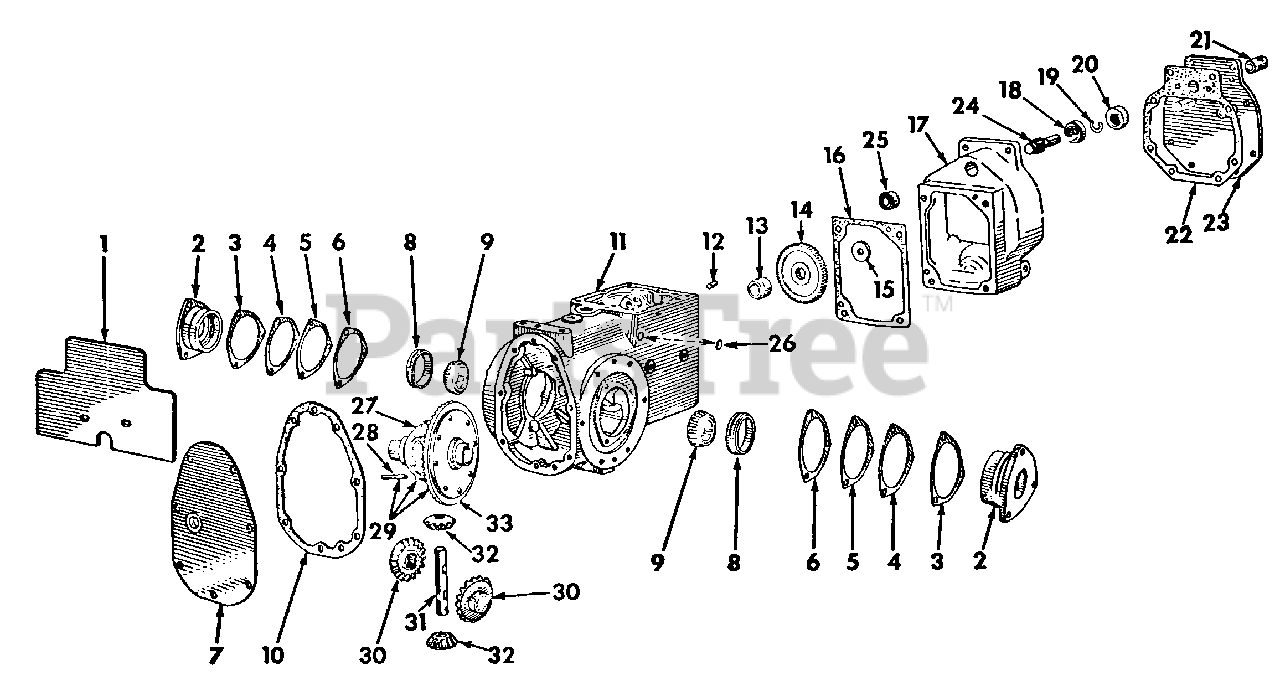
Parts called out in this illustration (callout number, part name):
1	Not used in this application
2	Cage w/Cup IH-ST974, Differential Brg
3	Shim, Differential Brg Retainer, .004
4	Shim, Differential Brg Retainer, .007
5	Shim, Differential Brg Retainer, .0149
6	Shim, Differential Brg Retainer, .0299
7	Plate Assy, Transmission Case Rear Cover
8	Bearing, Differential Cup
9	Bearing Assy, Differential Cone
10	Gasket, Transmission Case Rear Cover Plate
11	Case Assy, Transmission
12	Dowel, Transmission Case to Reduction Housing
13	Spacer, Driven Reduction
14	Gear, Reduction Drive -84T
15	Washer, 15/32 x 1-1/4 x 3/16
16	Gasket, Reduction Drive Housing
17	Housing, Reduction Drive
18	Bearing Assy, Reduction Drive Shaft Front Ball
19	Ring, Reduction Drive Shaft Brg Ext Snap
20	Seal, Reduction Drive Shaft Oil
21	Bushing, Clutch Shaft
22	Gasket, Reduction Housing Cover Plate
23	Plate Assy, Reduction Housing Cover
24	Shaft, Reduction Drive
25	Bearing Assy, Reduction Drive Shaft Rear
26	Plug, 11/16 Expansion
28	Pin, Differential Pinion Shaft Lock
29	Case w/Drive Gear, Differential
30	Gear, Differential Side
31	Shaft, Differential Pinion
32	Pinion, Differential -10T
33	Gear, Differential Drive -46T
